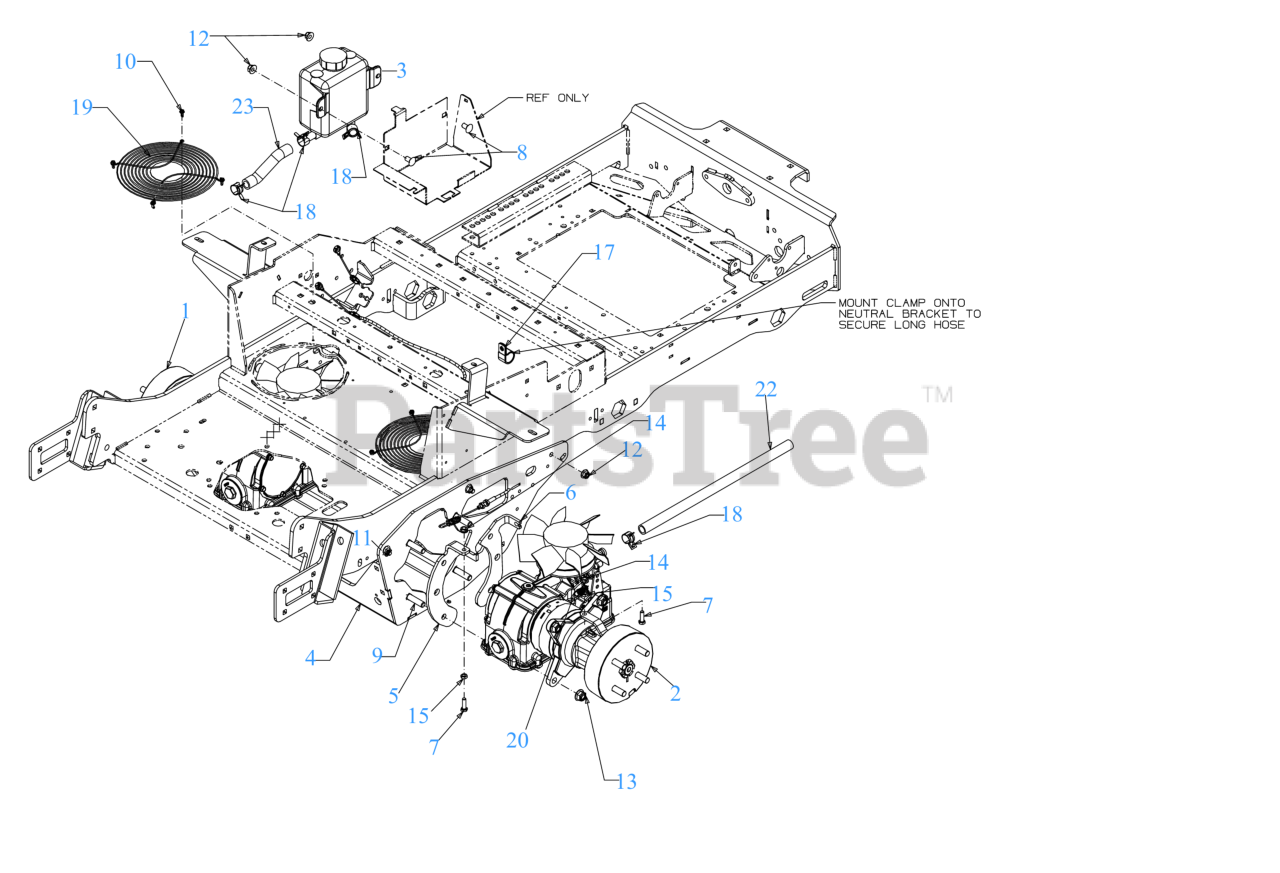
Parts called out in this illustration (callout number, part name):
1	TRANSMISSION ASSEMBLY PARKER (LH)
2	TRANSMISSION ASSEMBLY PARKER (RH)
3	HYDRO TANK ASSEMBLY
7	SCREW 5/16-18 x 1.0 GR5
8	CARRIAGE BOLT 3/8-16 x .750 GR5
9	CARRIAGE BOLT 1/2-13 GR5
10	SCREW 10-24 x 0.500
11	CARRIAGE BOLT 3/8-16 X1.25 GR5
14	HEX FLANGE NUT
17	HOSE CLAMP 1.0"
18	HOSE CLAMP
20	EXTENSION SPRING .500 OD x 1.71
22	OIL HOSE 5/8 ID x 18.00 LG
